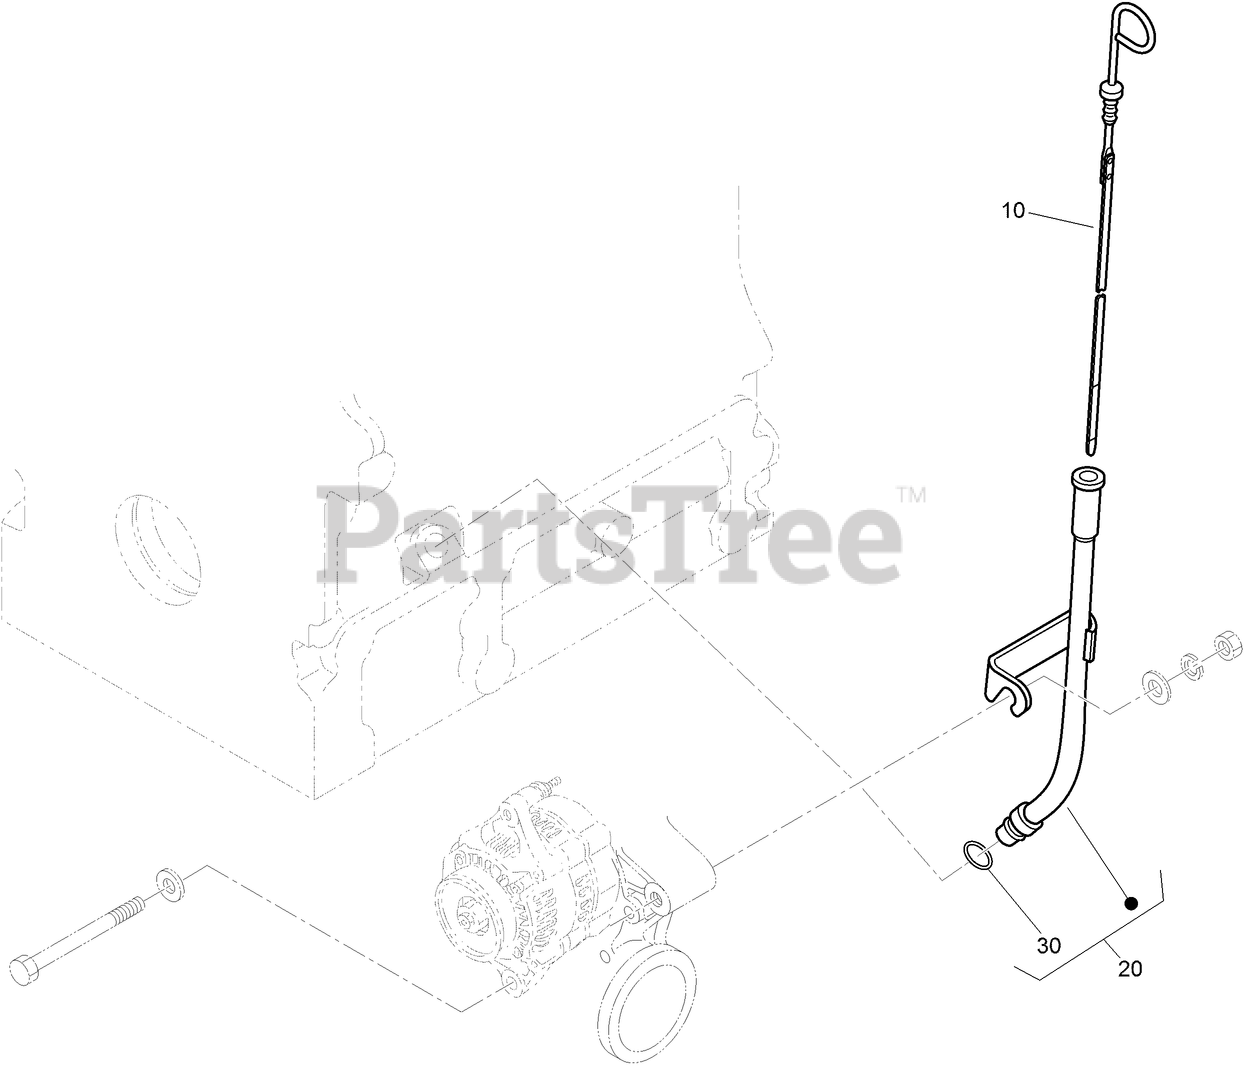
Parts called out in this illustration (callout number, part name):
10	GAUGE-OIL
20	OIL GAUGE GUIDE ASM
30	O-RING
